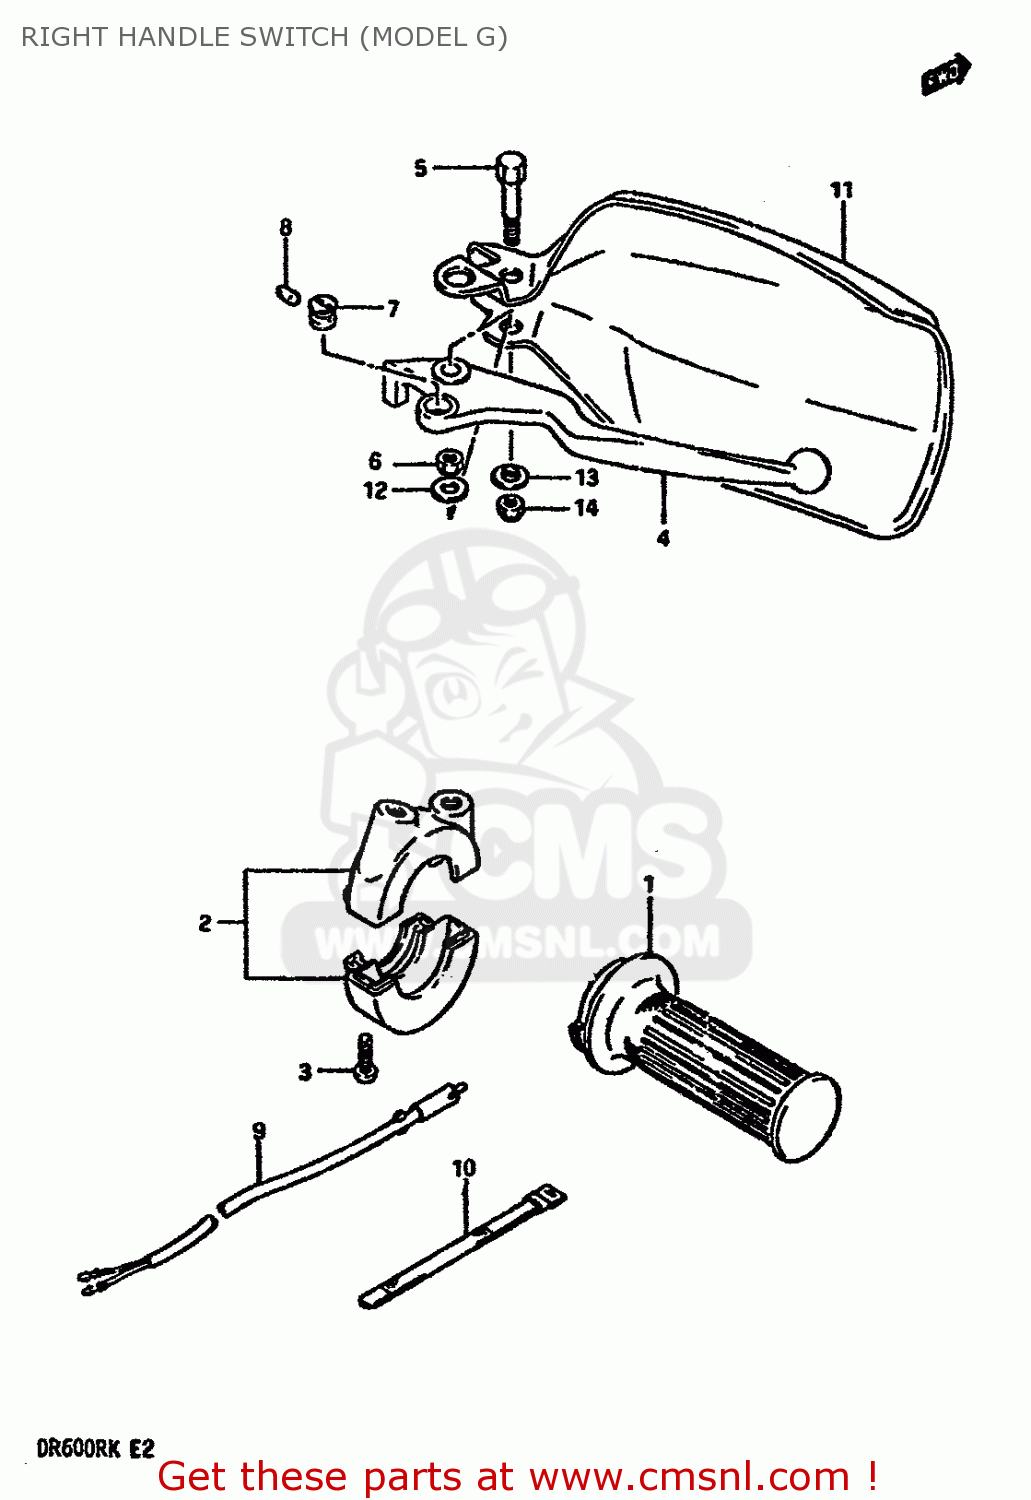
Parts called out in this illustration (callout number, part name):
1	GRIP,THROTTLE
2	CASE ASSY,THROTTLE
3	SCREW 5X20
4	LEVER,BRAKE
5	BOLT,LEVER PIVOT
6	NUT
7	ADJUSTER
8	ROD,PUSH
9	SWITCH ASSY,STOP
10	CLAMP(L:120)
11	COVER,KNUCKLE,R
12	WASHER(6.5X16X1.2)
13	WASHER
14	NUT 6MM
